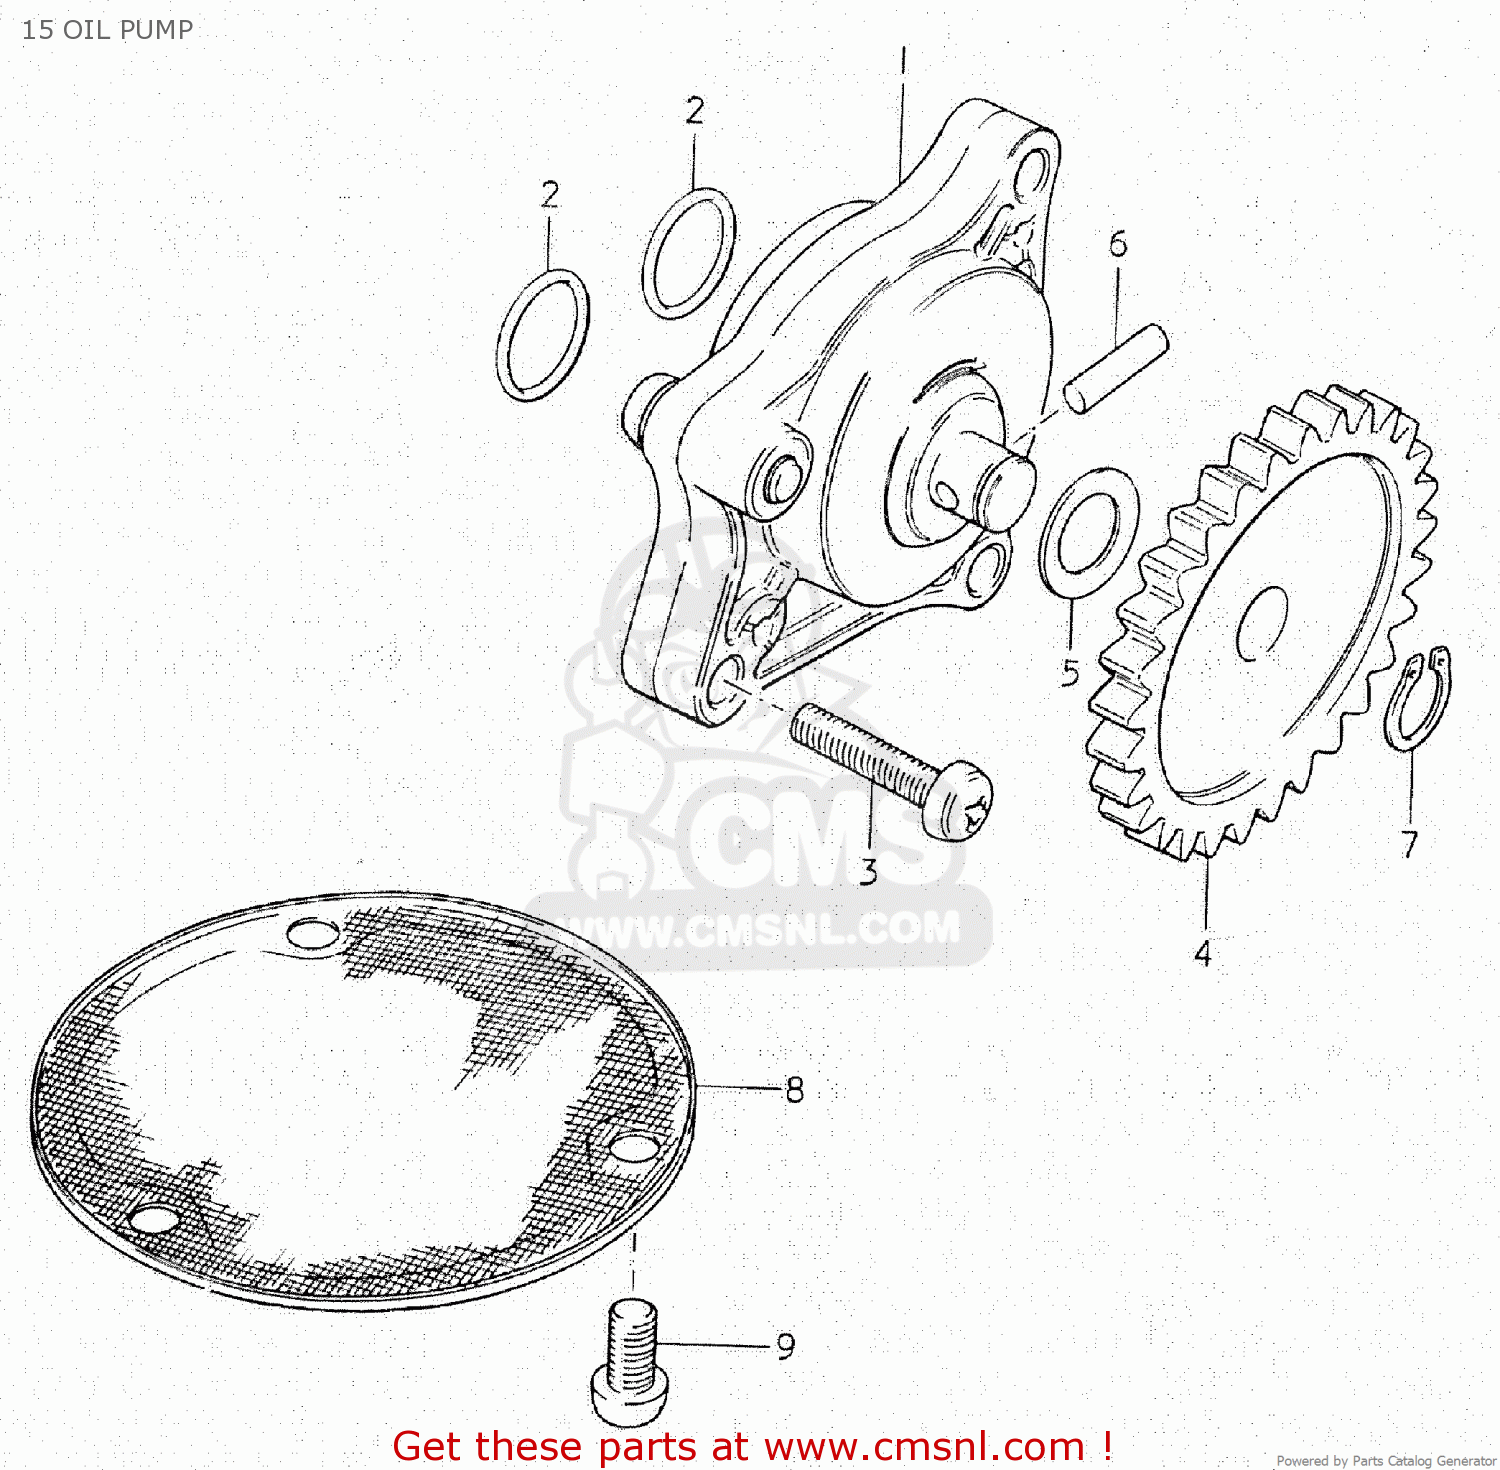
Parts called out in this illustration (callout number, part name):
1	PUMP ASSEMBLY,OIL
2	O RING(D:1.9,ID:13)
3	SCREW
4	GEAR,ENG OIL PUMP DRIVEN
5	SHIM
6	PIN(4X15.8)
7	CIRCLIP
8	STRAINER,ENGINE OIL
9	SCREW 6X12
